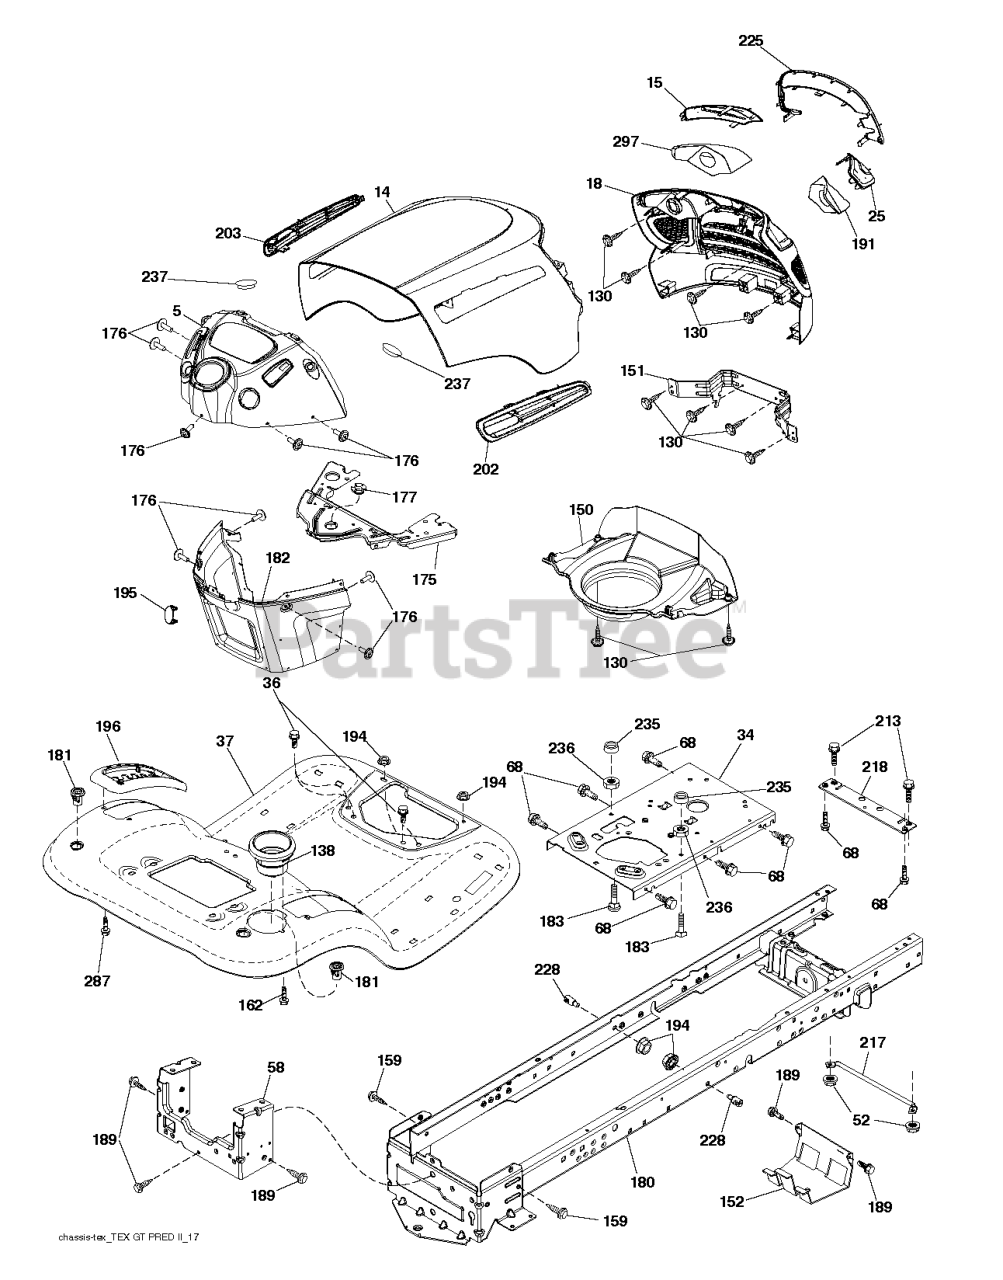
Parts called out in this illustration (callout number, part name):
5	DASH.UPPER.PREDATOR.YT/GT
14	HOOD.PNT.PREDATOR.YT/GT.BLACK
15	LENS.MCCULLOCH.GT.LH
18	GRILLE.PREDGT2.GEN
25	LENS.MCCULLOCH.GT.RH
34	PLATE.ENGINE.WELDED.CHASSIS
36	SCREW 5/16"
37	FENDER.TLT.W/CPH.428
52	Locknut, Hex w/Insert 5/16-18 Unc
58	DRAWBAR UPPER 2PC SMALL FENDER
68	SCR 5/16-18 X 1/2 SELFTAP ZN
130	SCREW.#10 X 0.750.BOS (2 2)
138	CUPHOLDER.TL.TEX.BLACK
150	PREDATOR.YT.GT.HOOD.AIR DUCT
151	BRACKET.PIVOT.PREDATOR
152	SHIELD.BROWNING.W/TEX
159	SCREW, 3/8-16X3/4
162	Screw, Hex Wsh Hi-Lo 1/4-1/2 (AYP part number)
175	PLATE.PNT.CROSSMEMBER.HUSQ/PRE
176	SCREW.#10-24X5/8.RN.QU
177	BUSHING STEERING
180	CHASS.WLDMNT.TL.12GA/2P.48/54
181	FEND/FTRST.PCH.CPH.NFW
182	DASH LOWER.HUSQ.PRED NO CRUISE
183	BOLT.5/16-18X1-1/4 FULL THD
189	SCREW
191	REFLECTOR.MCCULLOCH.GT.RH
194	NUT LOCK HEX FLANGE 5/16-18
195	PLUG.HOLE.DASH.LOWER.12V.BLK
196	CONSOLE.ASM.DECKLFT.BL/YBT.TLT
202	VENT.SIDE.HOOD.RH.PREDATOR.BLK
203	VENT.SIDE.HOOD.LH.PREDATOR.BLK
213	Bolt, Hex Head 5/16-18 UNC x 3/4 (AYP part number)
217	ROD.PIVOT.HOOD
218	X-PIECE.HOOD.STOP.NON/
225	TRIM.RING.MCCULLOCH.GT
228	STUD.FASTNER.W/ANTI-ROTATE
235	SPACER FENDER
236	NUT.CENTERLOCK.5/16-
237	PLUG.MOUNT.CARGO.BLK
287	SCREW 1/4X20
297	REFLECTOR.MCCULLOCH.GT.LH
